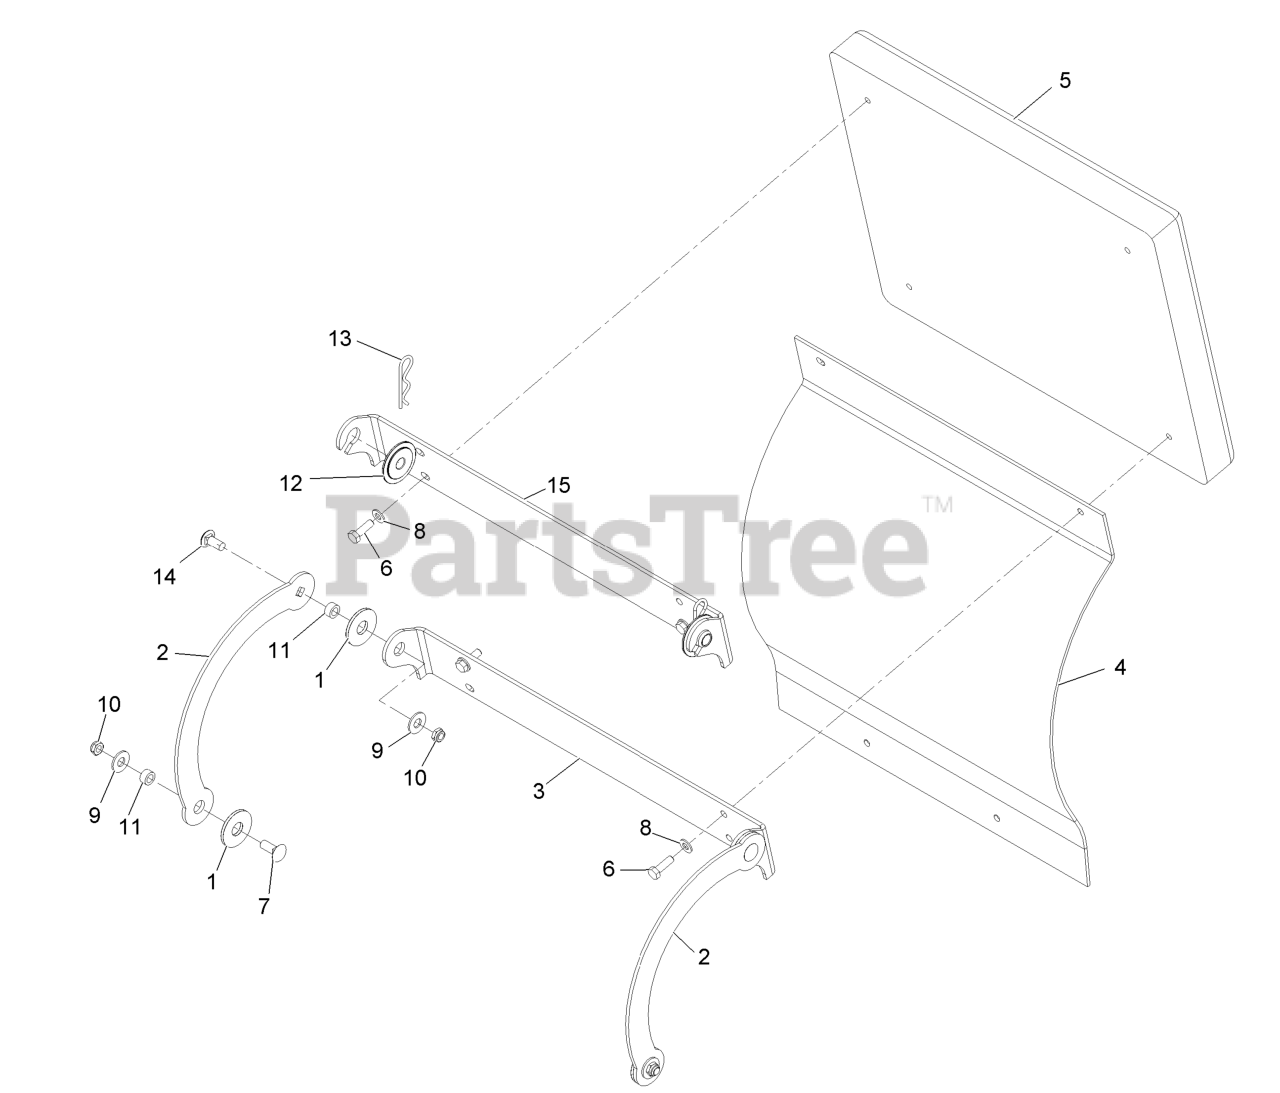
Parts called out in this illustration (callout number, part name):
1	WASHER-FRICTION, COMPOSIT
3	HINGE-PAD
5	PAD,GREY CUSHION
6	SCREW-HH, THREAD LOCKING
7	BOLT-CARR
8	WASHER-PLAIN
9	WASHER-FLAT
11	SPACER
12	SLIDE-BUSHING
13	PIN-HAIR
14	SCREW-CARR
15	HINGE-PAD
